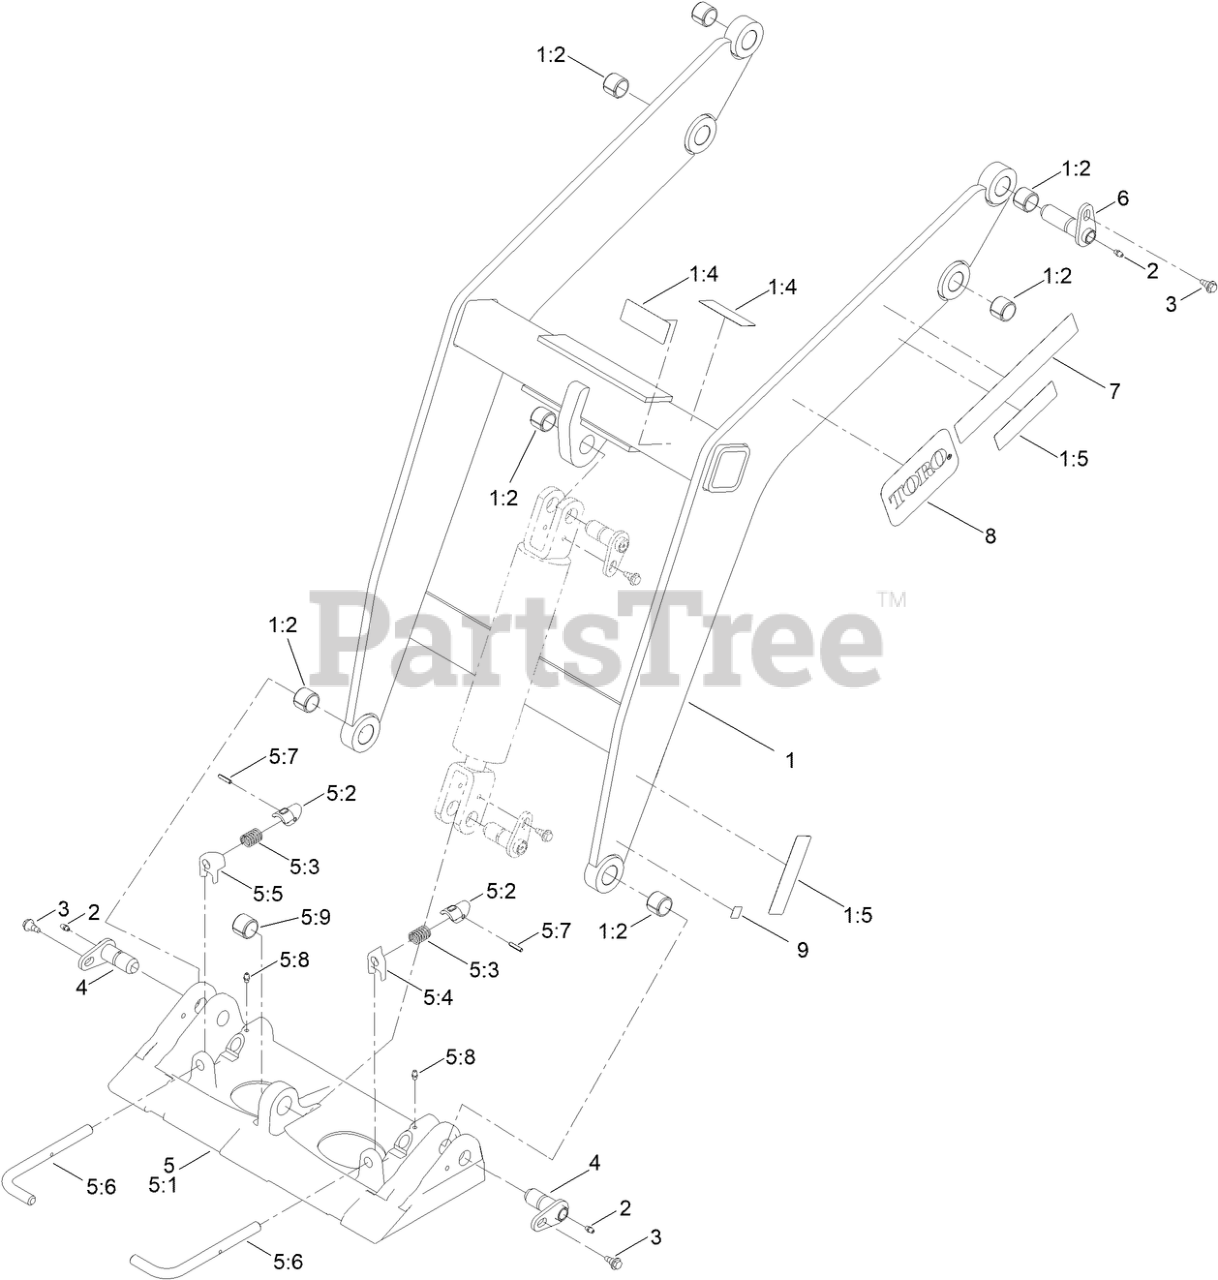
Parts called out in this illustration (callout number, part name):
1	LOADER ASM
1:2	BUSHING-TENSION
1:4	DECAL-WARNING, NO RIDER
1:5	DECAL-WARNING, CRUSHING
2	FITTING-GREASE
3	BOLT-SHOULDER
4	PIN-PIVOT
5	QUICK ATTACH ASM
5:1	MOUNT-QTACH
5:3	SPRING-COMPRESSION
5:4	STOP-RH
5:5	STOP-LH
5:6	PIN-LOCKING
5:7	PIN-GROOVED
5:8	FITTING-GREASE
5:9	BUSHING-TENSION
6	PIN-PIVOT
8	DECAL
9	DECAL-POINT, LIFT
